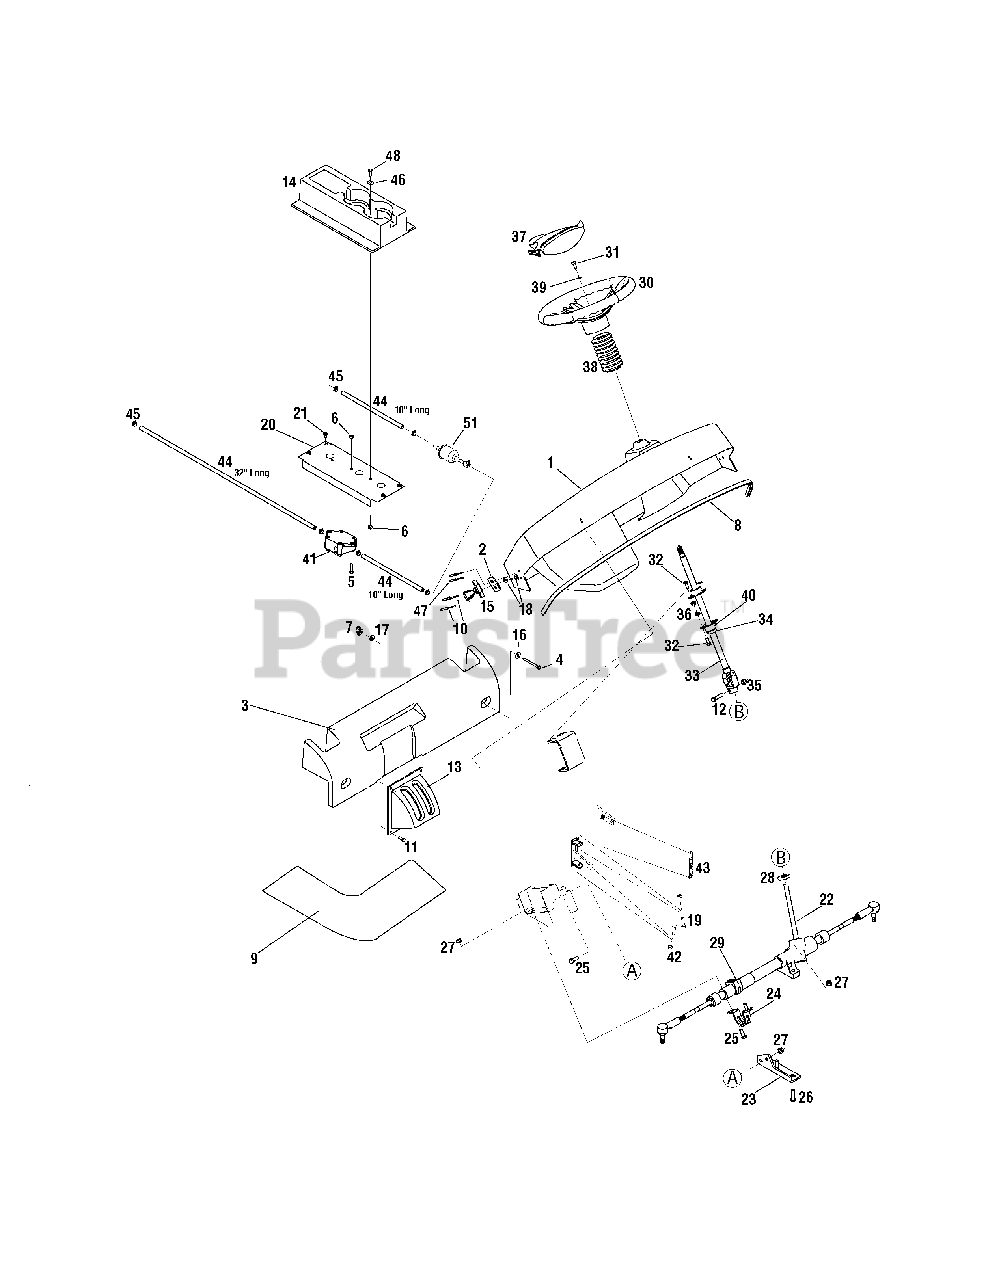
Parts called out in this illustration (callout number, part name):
1	Dash Assembly
2	Hood Mounting Plate
3	Panel Cover
4	Hex Screw, 1/4-20 x 2.75
5	Hex Screw, 1/4-20 x.75, Gr5
6	Hex Lock Nut, Nylon, 1/4-20
7	Wing Nut, 1/4-20
8	Trim, Bulb Seal, 1/4
9	Foot Pad, Abrasive
10	Rivet, Pop,.187
11	Rivet, Pop,.188
12	Hex Screw, 3/8-16, 1.75, GR5
13	Panel, Shift Cover
14	Console, Cup Holder
15	Handle, Latch
16	Flat Washer, 349 x.875 x.04
17	Washer, Flat,.28 x.74 x.063
18	Washer, Flat,.194 x.62 x.063
19	Hex Screw, 5/16-18 x 1.25
22	Gear Assembly, Steering
25	Hex Screw, 3/8-16, 1.00, Gr8
26	Hex Screw, 3/8-16, 1.50, Gr8
27	Nut, Flange Lock, 3/8-16
28	Grommet, Steering Shaft
29	Bushing, Rubber
30	Wheel, Steering
31	Hex Screw, 5/16-18,.75, Gr5, Patch
32	Hex Screw, 5/16-18, .75, Gr5
33	Shaft, Steering, 5/8 Spline
34	Collar, .75
35	Nut, Hex Lock Nylon, 3/8-16
36	Nut, Flange Lock, 5/16-18
37	Cover, Steering Wheel
38	Bellow, Steering, 4.75 Lg
39	Washer, Bell,.340 x.872 x.060
40	Bearing, Flange,.75 ID, Self-Aligning
41	Pump, Fuel
42	Hex Nut, 5/16-18
43	Extension Spring
44	Fuel Line Hose
45	Clamp, Hose
46	Washer, Bell .39 x 1.38 x .062
47	Pop Rivet, 3/16 dia.x .450
48	Self-tap Screw5/16-18
49	Hood Cable Mount Bracket (Not Pic.)
50	Hood Cable (Not Pictured)
51	Fuel Filter
